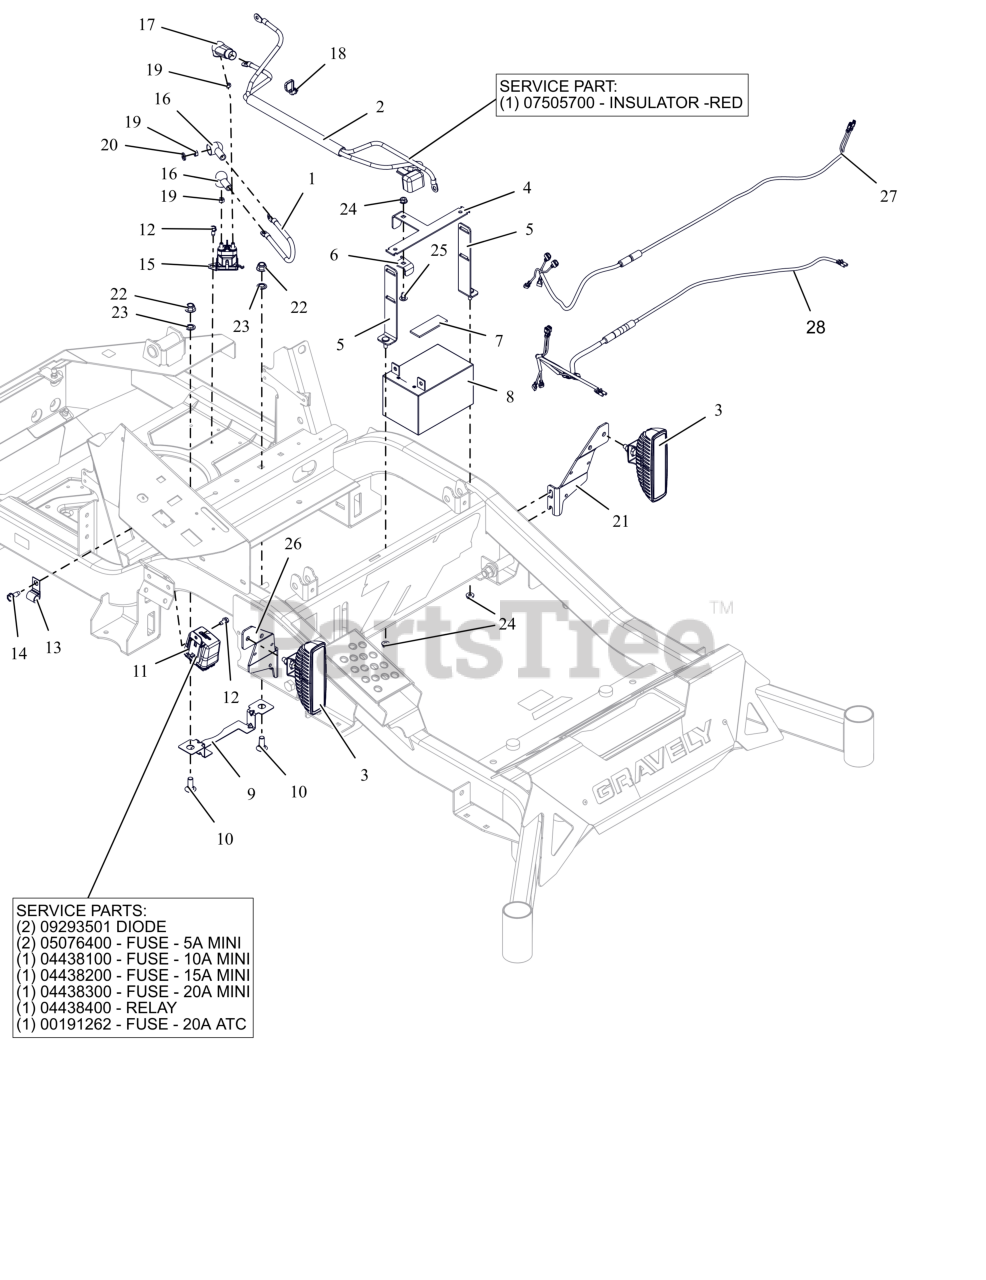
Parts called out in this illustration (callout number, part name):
1	CABLE, POS W/(2)1/4 RING 9.0LG
1	INSULATOR
2	HARNESS, BATTERY HD
3	LIGHT, 6 LED- NO CONN.
4	BRKT, BATTERY TIE DOWN
5	WMT,BATTERY MOUNT HOLD DOWN
6	BRKT, BATTERY HOLD
7	PAD,RBR 1.0"X3.0" W/ADHESIVE
8	BATTERY, 12V 12A -190CCA
9	GUARD, ELECTRICAL HARNESS
10	BLT, RHSN .38-16X1.00 G5 ZCC
11	HARNESS, WIRE
11	DIODE, CONNECTOR SHELL
11	FUSE, 5 AMP MINI-ATC
11	FUSE,10 AMP MINI-ATC
11	FUSE,15 AMP MINI-ATC
11	FUSE,20 AMP MINI ATC
11	RELAY,MICRO5 TERML W/RESISTOR
11	FUSE, 20 AMP BLADE S/O
12	SCR-TAP .25-20X.50 HWH ZCC
14	SCR,TAP .312-18X.75 HWH TR ZCC
15	SOLENOID, STARTER (SEALED)
16	BOOT, EYELET TERMINAL
17	BOOT, .65ID POS
18	CABLE TIE W/ TREE (.25 HOLE)
19	NUT-STD M6-1.0 ZCC
20	WSHR,LK-REG .312X.078 ZCC
21	BRKT- LIGHT MTG - LH
22	NUT,NYL-FLG .38-16 GF ZCC
23	NUT-PUSH .38 DIA. PAL ZINC
24	NUT-LK-TOP-FLG .250-20 GF ZCC
25	BLT, RHSN .25-20X.500 G5 ZCC
26	BRKT- LIGHT MTG - RH
27	HARNESS, USB PORT
28	HARNESS, HEAD LIGHT (HD)
